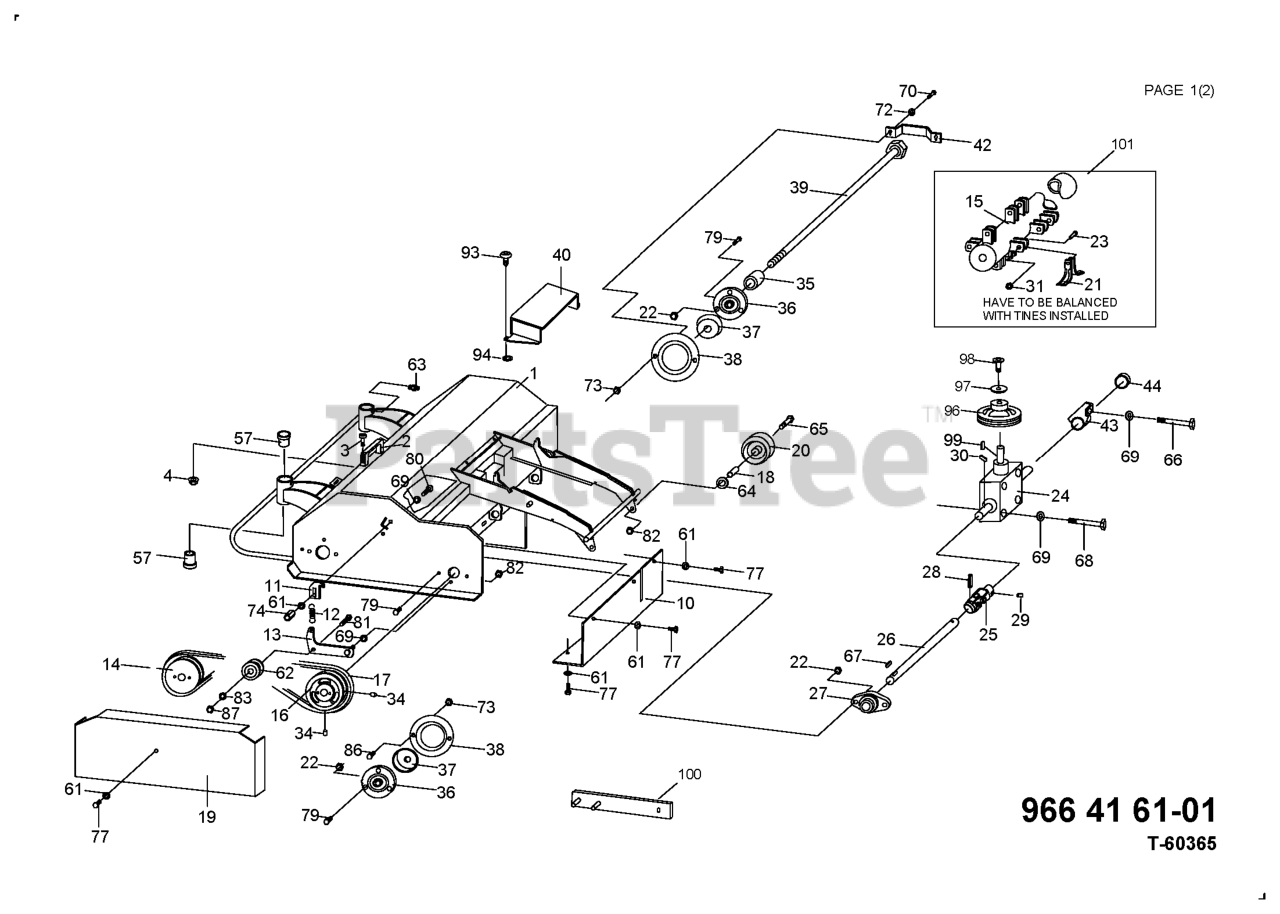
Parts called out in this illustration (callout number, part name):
4	NUT LOCKING
18	COLLAR
19	BELT GUARD
20	SUPPORT WHEEL
26	DRIVE SHAFT
42	HAND GUARD
44	DUST COVER
